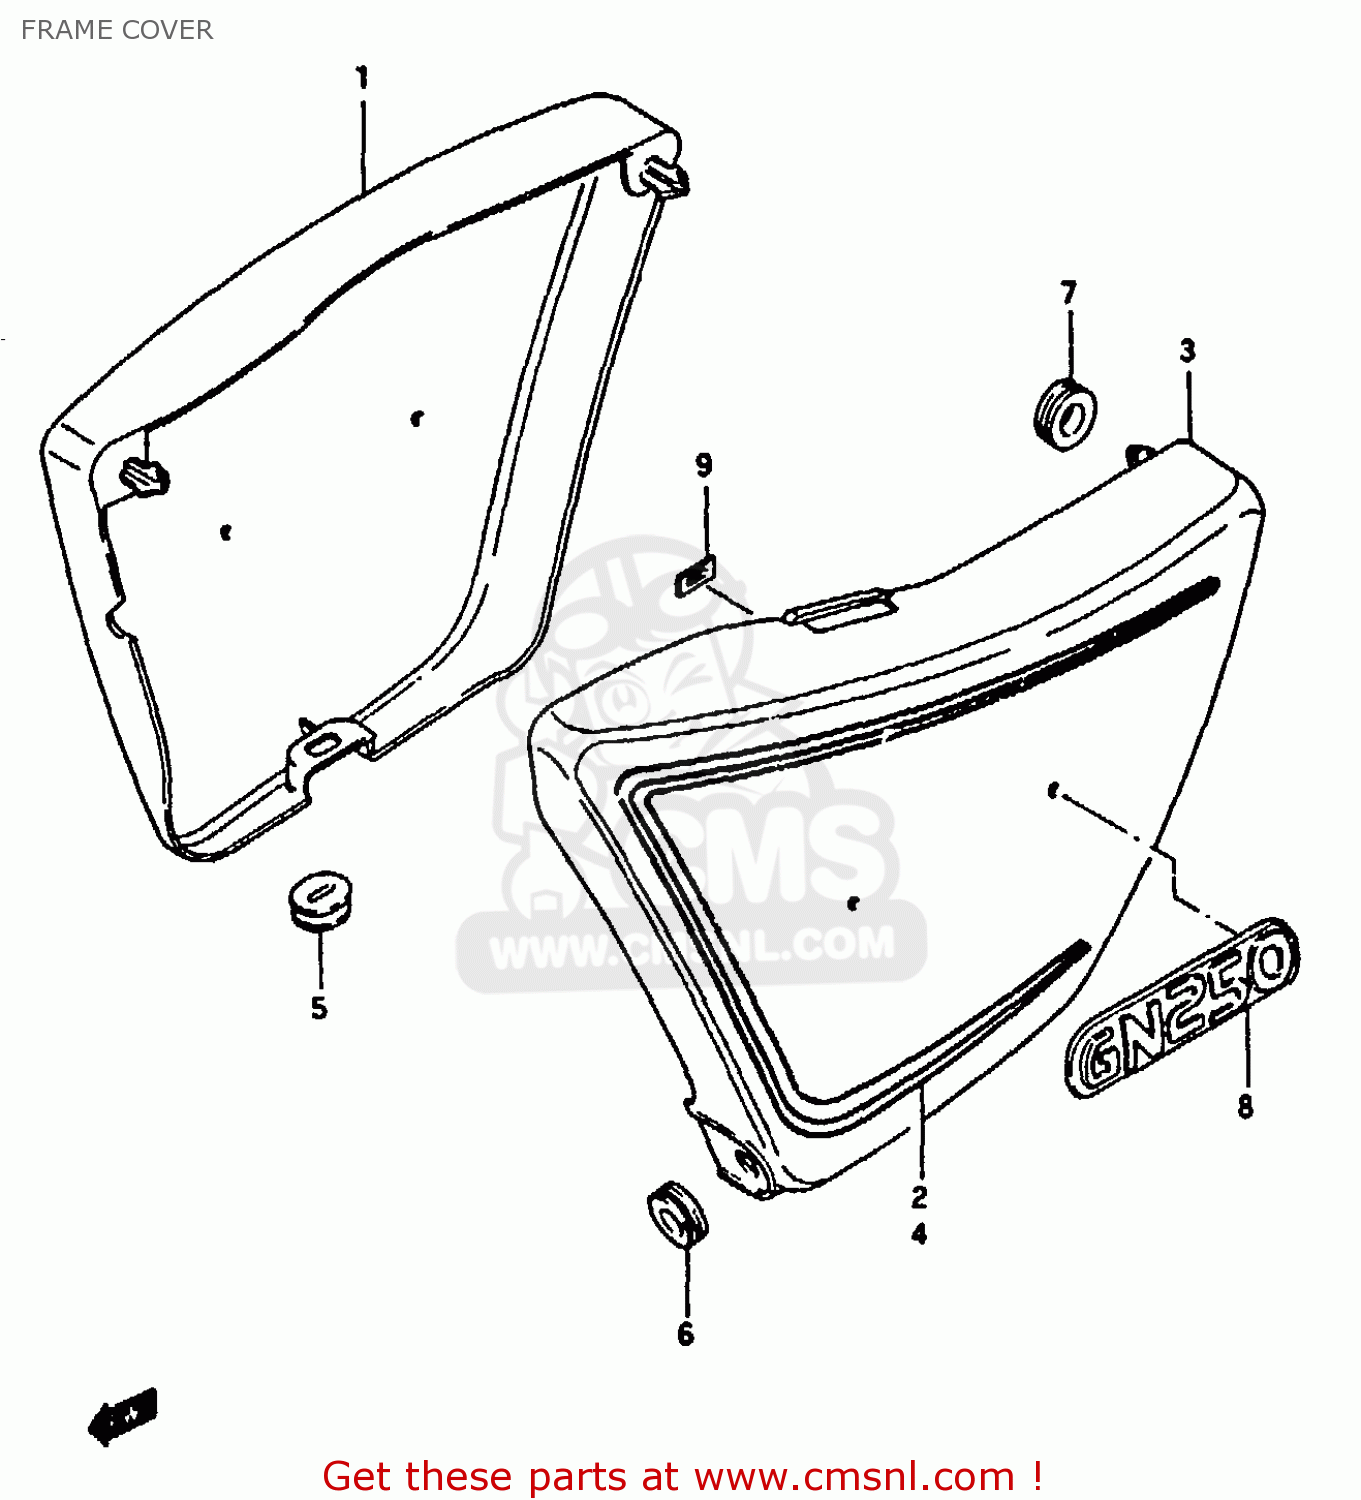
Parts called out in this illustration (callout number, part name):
1	COVER,FRAME,RIGHT
2	TAPE SET,FRAME COVER,R
3	COVER,FRAME,LEFT
4	TAPE SET,FRAME COVER,L
5	CUSHION
6	CUSHION
7	CUSHION
8	EMBLEM,GN250
9	NUT
